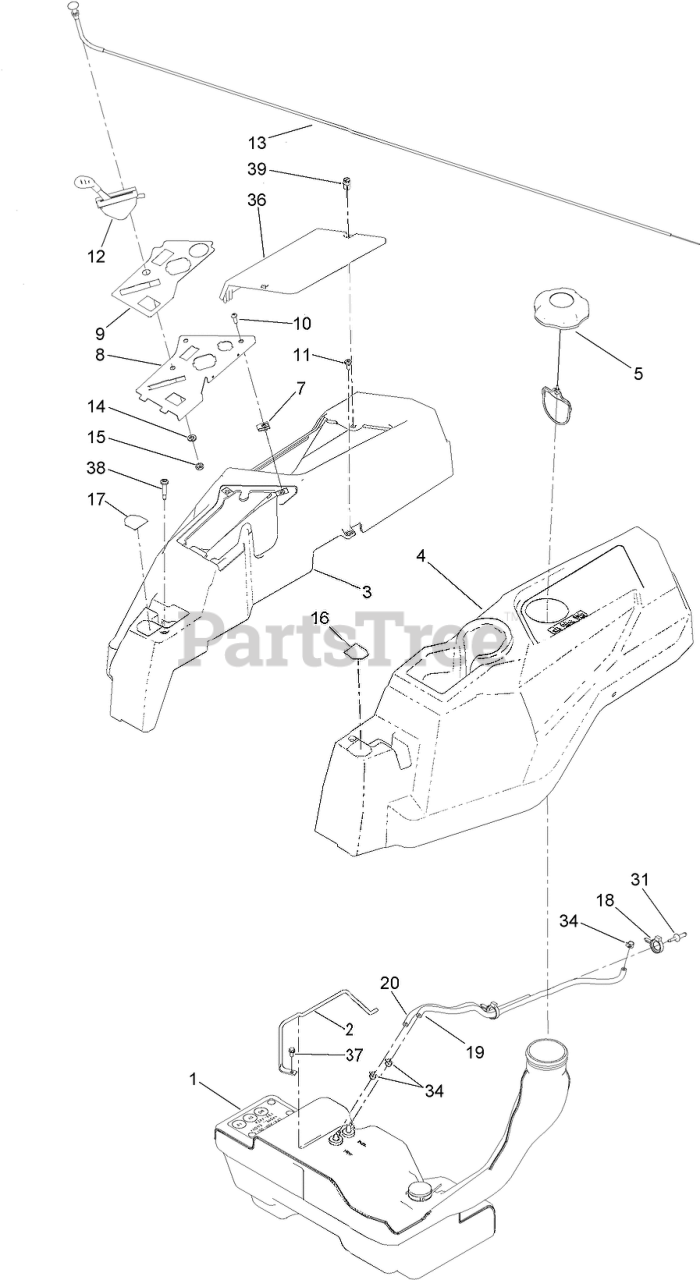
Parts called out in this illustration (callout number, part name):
1	FUEL TANK ASM
2	ROD-HOLD DOWN
3	POD-RH
4	POD-LH
5	CAP-FUEL, RATCHETING
8	PANEL-CONTROL
9	DECAL-CONTROL W/CHOKE
10	SCREW-PRH
11	SCREW-SHOULDER
12	CABLE-THROTTLE
13	CABLE-CHOKE
14	WASHER-LOCK
15	NUT-HJ
16	DECAL-LEVER, CONTROL (LH)
17	DECAL-LEVER, CONTROL (RH)
18	CLAMP-HOSE
19	HOSE-FUEL
20	HOSE-FUEL
31	ADAPTOR-ORIFICE
34	CLAMP-HOSE
36	COVER-BATTERY
37	SCREW-HWH
38	SCREW-SHOULDER
39	FASTENER
